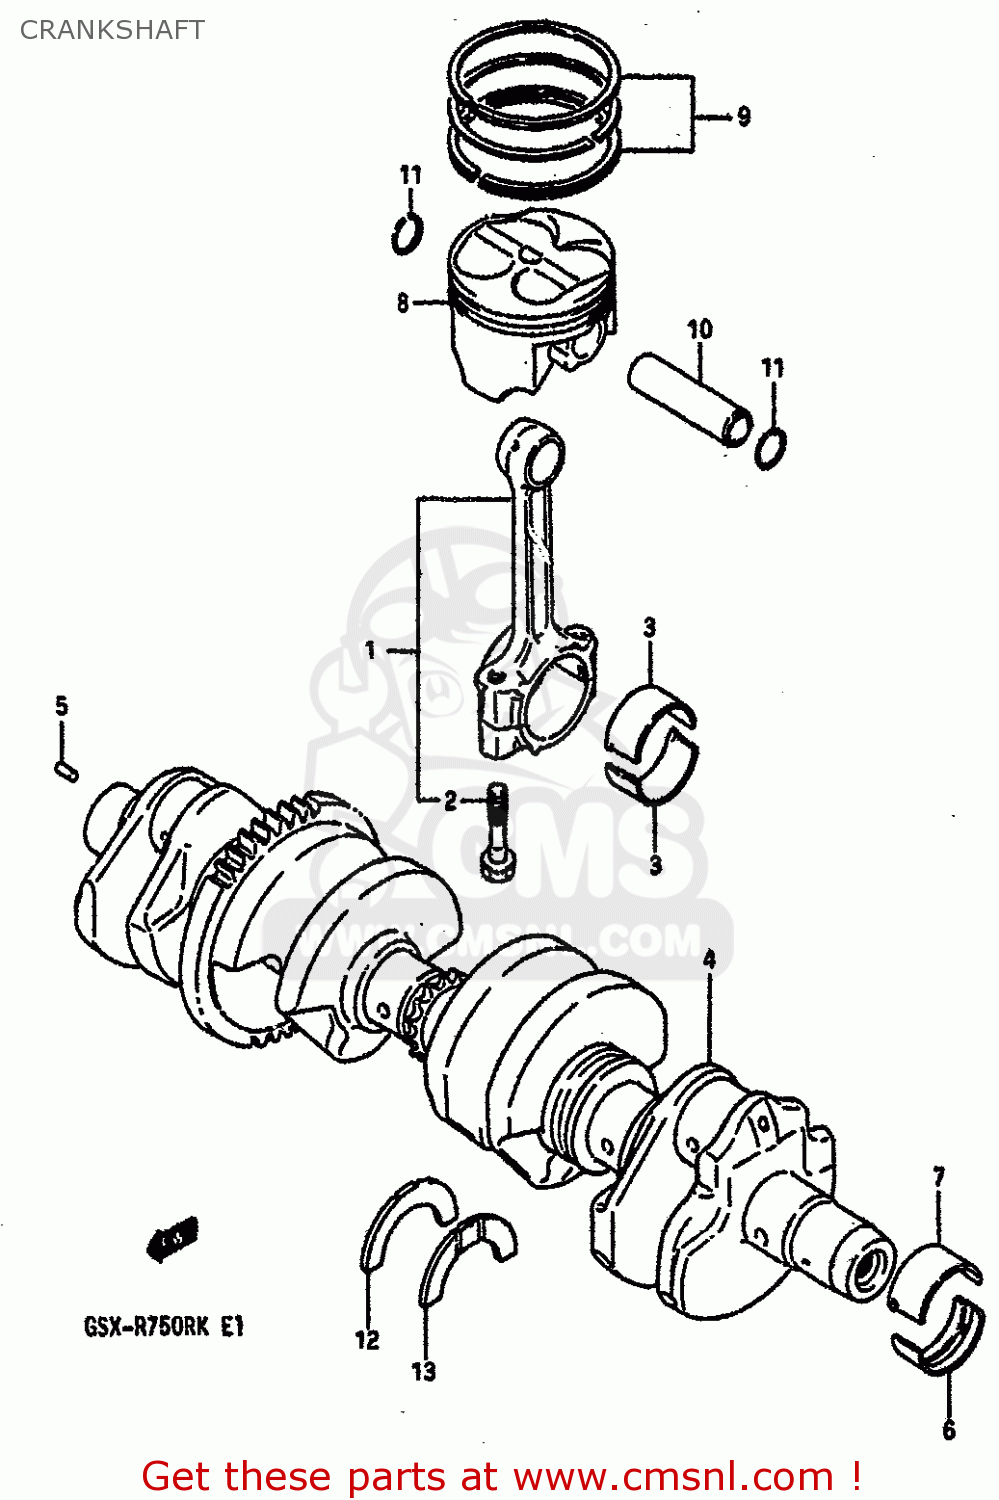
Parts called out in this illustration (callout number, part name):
1	ROD ASSY,CONNECTING
2	BOLT
3	BEARING,CRANK PIN
4	CRANKSHAFT
5	PIN
6	BEARING,CRANKSHAFT LWR
7	BEARING,CRANKSHAFT UPR
8	PISTON
9	RING SET,PISTON
10	PIN,PISTON
11	CIRCLIP
12	PLATE,CRANK THRUST
13	PLATE,CRANK THRUST
